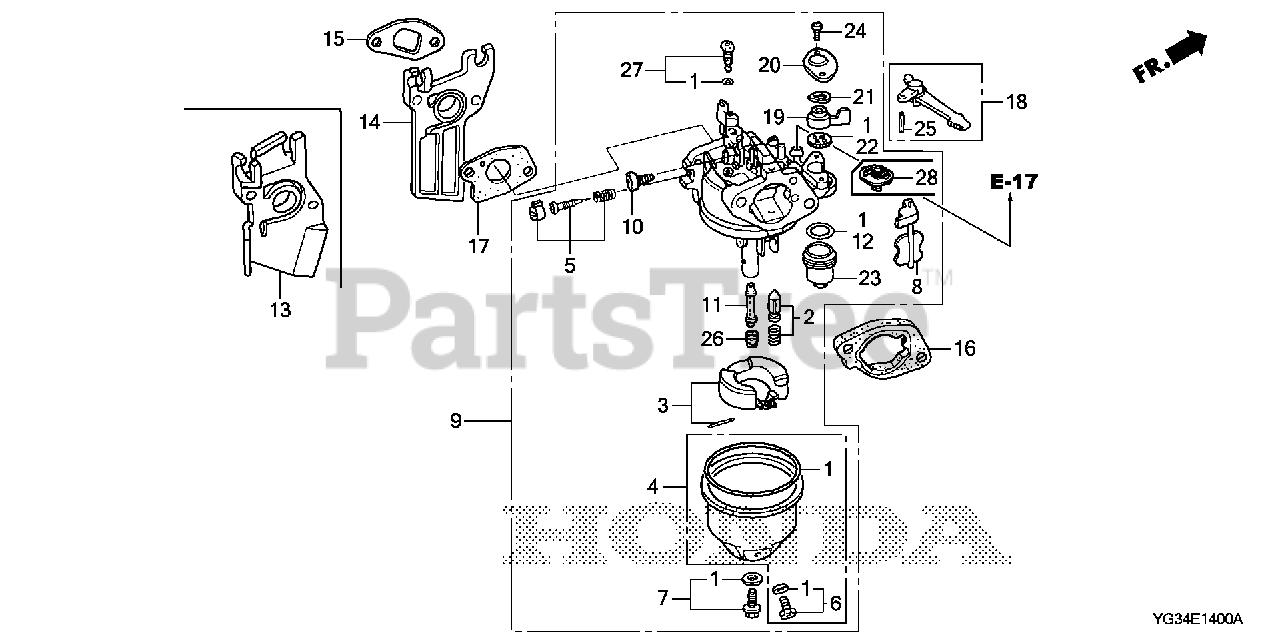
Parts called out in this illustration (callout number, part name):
1	GASKET SET
2	VALVE SET, FLOAT (SEAT NOT INCLUDED)
4	CHAMBER SET, FLOAT
5	SCREW SET, PILOT
6	SCREW SET, DRAIN
9	CARBURETOR ASSY. (BE54D A)
10	SCREW, THROTTLE STOP
11	NOZZLE, MAIN
12	GASKET, FUEL STRAINER CUP
14	INSULATOR, CARBURETOR
15	GASKET, INSULATOR
16	SPACER, CARBURETOR
17	GASKET, CARBURETOR
18	LEVER, CHOKE (STD)
19	LEVER, PETCOCK
20	PLATE, LEVER SETTING
21	SPRING, PETCOCK LEVER
22	GASKET, PETCOCK
23	CUP, FUEL STRAINER
24	SCREW, PAN (3X6)
25	PIN, SPRING (2X12)
26	JET, MAIN (#62)
26	JET, MAIN (#68)
26	JET, MAIN (#65)
27	JET SET, PILOT (#35)
28	FILTER, CUP
